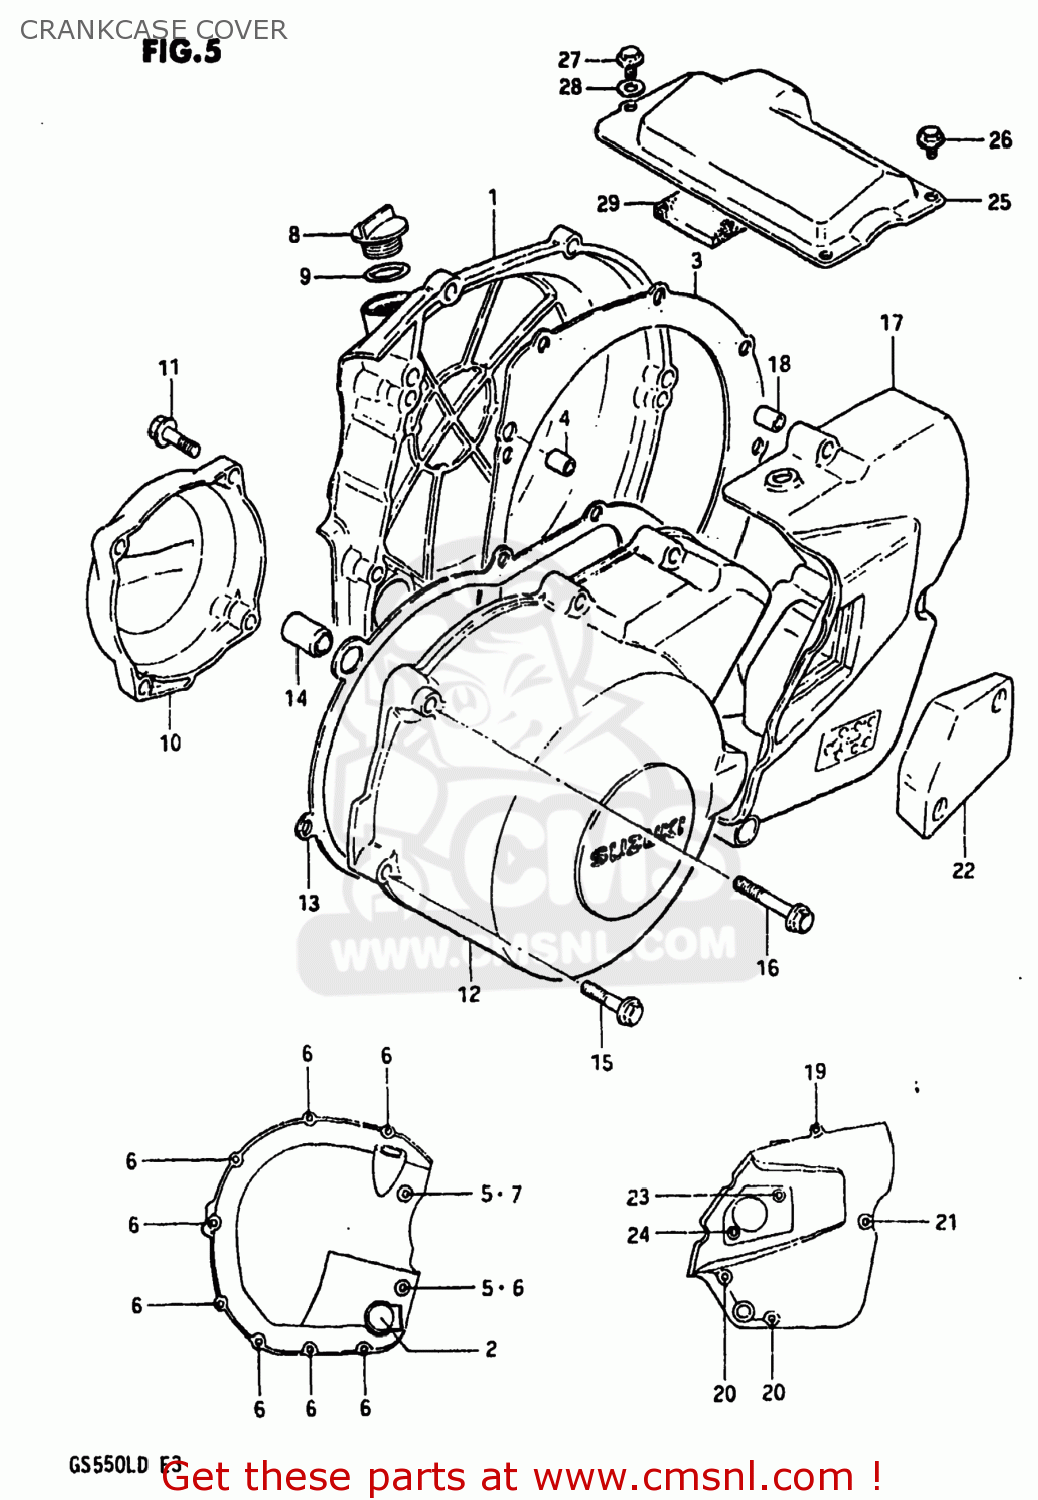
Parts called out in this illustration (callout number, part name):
1	COVER,CLUTCH
2	LENS,OIL LEVEL CHECK
3	GASKET,CLUTCH COVER (MCA)
4	PIN
5	WASHER
6	BOLT
7	BOLT (6X35)
8	PLUG(20X10)
9	O RING(D:3.1,ID:16.8)
10	COVER,CONTACT BREAKER
11	BOLT
12	COVER
13	GASKET,MAGNETO COVER (MCA)
14	PIN (11X20)(SUS)
15	BOLT (6X30)
16	BOLT
17	COVER,ENGINE SPROCKET
18	PIN
19	BOLT (6X40)
20	BOLT (6X55)
21	BOLT
22	CAP,CLUTCH RELEASE ADJUST
23	SCREW 5X12
24	SCREW
25	COVER,STARTER MOTOR
26	BOLT
27	BOLT
28	WASHER
29	DAMPER,STARTER MOTOR CLUTCH
